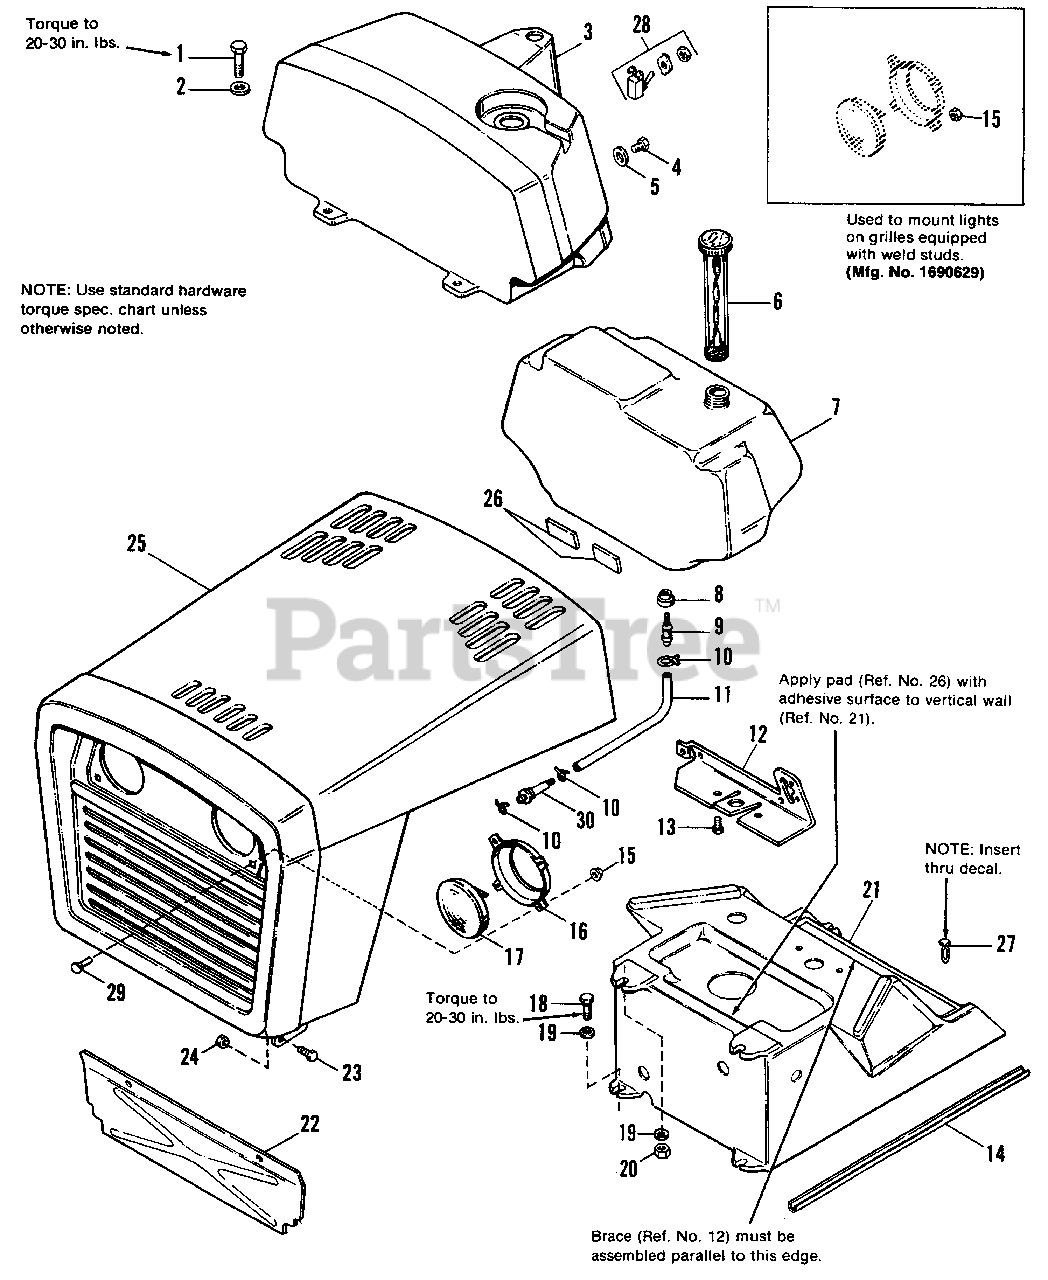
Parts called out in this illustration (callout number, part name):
1	CAPSCREW, Hex Hd., 1/4-20 x 1-1/4
2	WASHER, Plain, 1/4
3	DASH BOARD, Top
4	SCREW, #14 x 3/4
5	WASHER, Plain, 3/16
7	TANK ASSY., Fuel
10	CLAMP, Hose
12	BRACE, Dash
13	SCREW, Hex, Taptite, 1/4-20 x 1
14	EDGING, Lower Dash
15	LOCKNUT, Pal, #10-24 (Qty. 8 on 1690629 only)
16	BRACKET, Support, Headlight
17	LAMP, Sealed Beam, G.E. #4411-1
18	SCREW, Hex, Taptite, 1/4-20 x 1
19	LOCKWASHER, Dished Type, 1/4
20	LOCKNUT, Hex, 1/4-20
21	DASH BOARD, Bottom
22	BAFFLE, Engine, Front
23	CAPSCREW, Hex Hd., 3/8-16 x 7/8
24	LOCKNUT, Hex, 3/8-16
25	HOOD & GRILLE ASSY.
27	CLIP, Canoe
28	SWITCH, Toggle
29	BOLT, Carriage, #10-24 x 1/2
30	FILTER, Fuel
